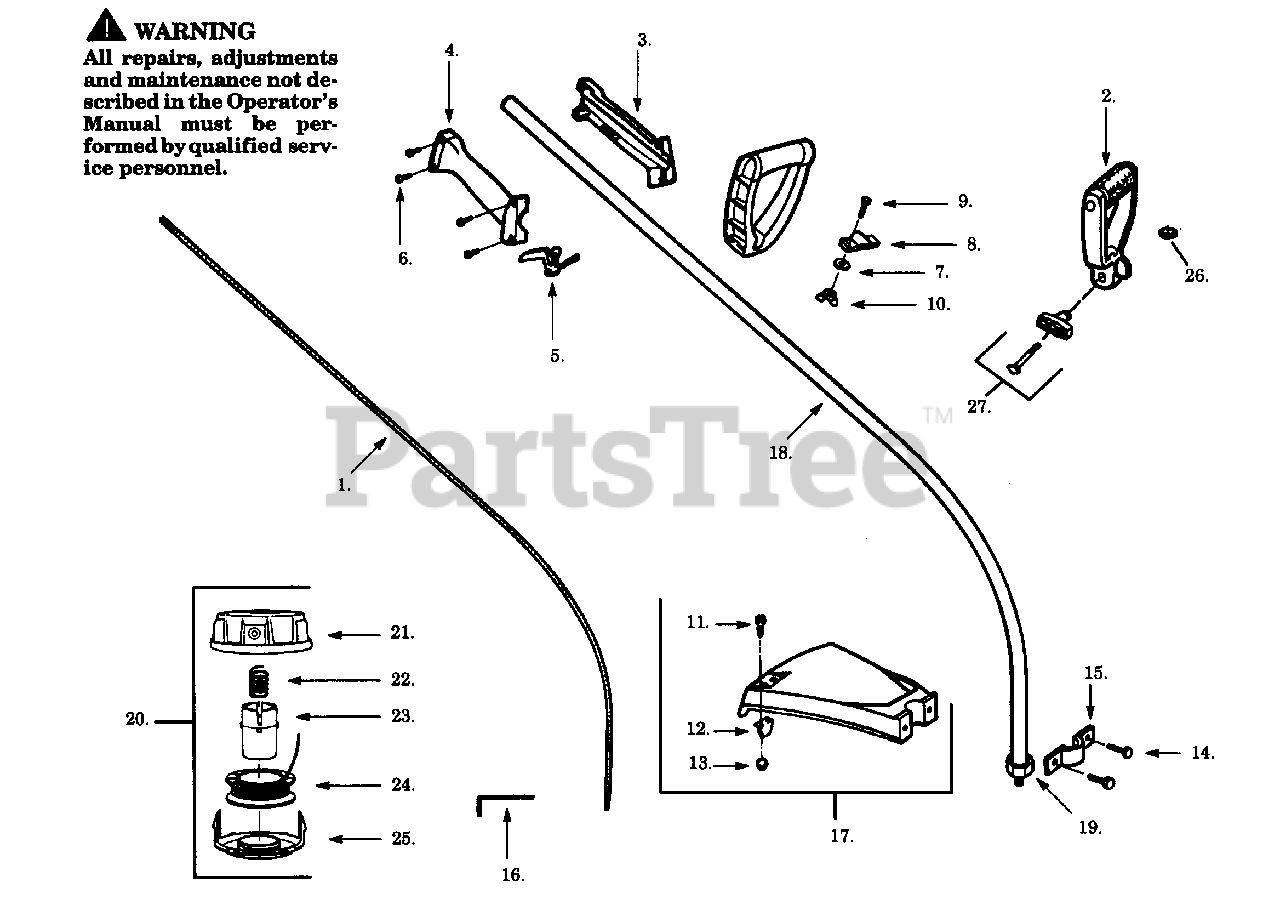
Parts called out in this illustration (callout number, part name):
1	Drive Shaft
3	Throttle Hsg. (Left)
4	Throttle Hsg. (Right)
5	Throttle Lever
12	Line Limiter
13	Locknut
14	Screw
15	Bracket Shield
16	Hex Wrench (5/32)
17	Shield Kit Ass'y.
18	Drive Shaft Hsg.
19	Dust Cup
20	Cutting Head Ass'y. (Inc. 21-25)
21	Hub Ass'y.
23	Release Button
24	Spool w/Line
27	"T" Handle Ass'y.
